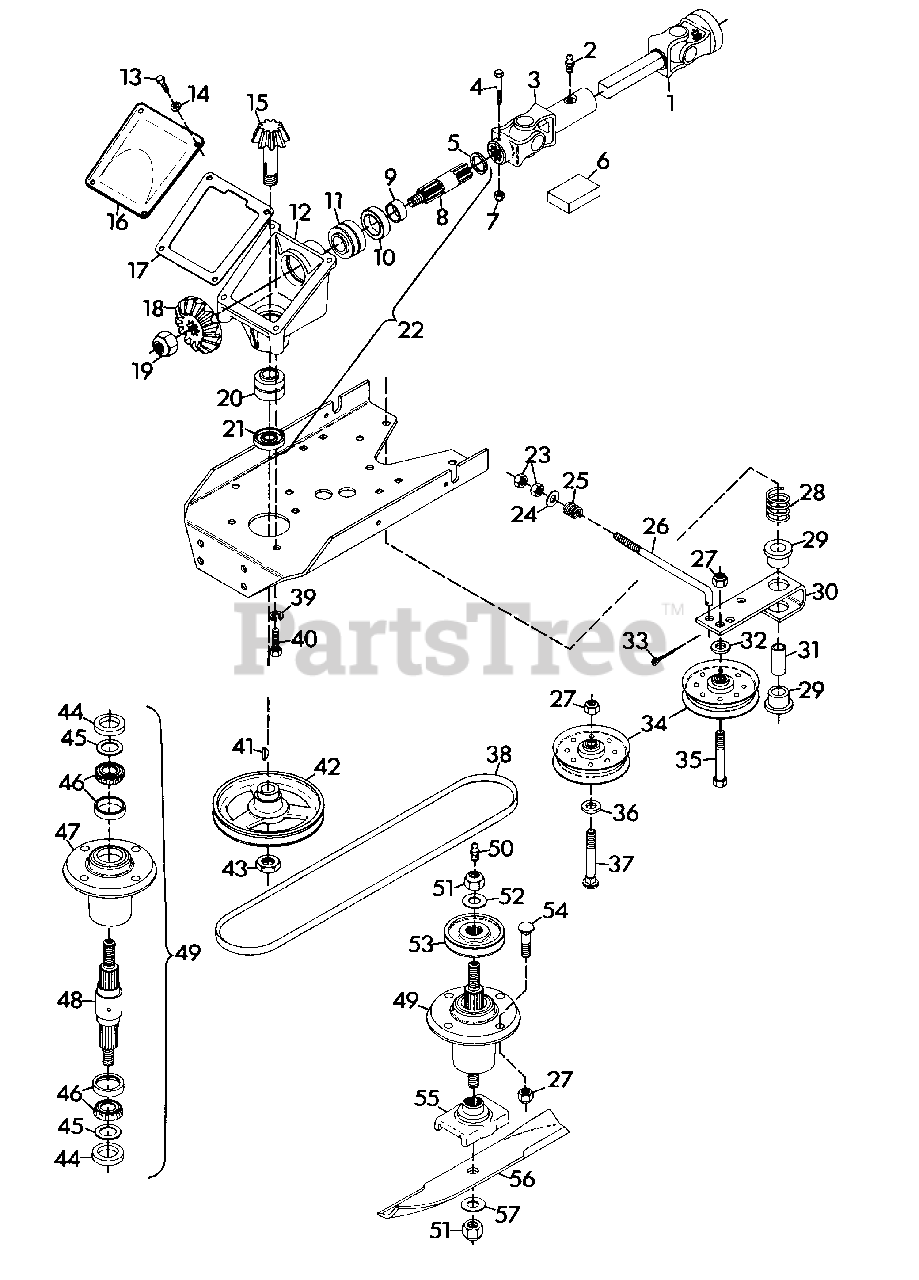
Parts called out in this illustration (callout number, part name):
1	SHAFT, PROP. SQ. BAR
2	FITTING, LUBE 1/4-28
3	U-JOINT, FEMALE END
4	BOLT, HEX 1/4-20X2
5	RING, RETAINING 1.000 SHAFT
6	KIT, REPAIR UNIVERSAL JOINT ROCKWELL STD.
6	KIT, REPAIR UNIVERSAL JOINT NEAPCO 1605X
7	NUT, LOCK 1/4-20
8	SHAFT, DRIVE
9	SPACER
10	SEAL, OIL 1.25X1.987X.250
11	ASSEMBLY, BEARING 1.000X1.980X1.243
12	CASTING, GEAR BOX
13	BOLT, HEX 1/4-20X.50
14	WASHER, LOCK 1/4
15	SHAFT, GEAR PINION
16	COVER, GEAR HOUSING
17	GASKET, GEAR HOUSING
18	GEAR, BEVEL
19	NUT, LOCK 3/4-10
20	ASSEMBLY, BEARING .750X1.781X1.499
21	SEAL, OIL 1.250X1.686X.313
22	ASSEMBLY, DRIVE 50" MOWER
23	NUT, HEX 3/8-24
24	WASHER, FLAT .406X.812X.065
25	SPRING, COMP. TYPE 1X.78X338 LB/IN
26	ROD, IDLER
27	NUT, LOCK 3/8-16
28	SPRING, COMP.
29	BUSHING, NYLON .760X1.00X.600
30	ARM, IDLER PIVOT
31	SPACER
32	SPACER, IDLER .406X.750X.188
33	PIN, COTTER 3/32X1.00
34	SHEAVE, IDLER
35	BOLT, HEX 3/8-16X2.00
36	WASHER, FLAT .438X1.000X.083
37	BOLT, 3/8-16X1.75 RD HD SQ NK
38	BELT, V .500X.312X126.3
39	WASHER, LOCK 1/2
40	BOLT, HEX 1/2-13X1.00
41	KEY, WOODRUFF .188X.625 HARD
42	SHEAVE, 1/2X6.50
43	NUT, JAM 3/4-10 HEX HEAVY
44	SEAL, STEEL
45	WASHER, FLAT .975X1.970X.030
46	ASSEMBLY, BEARING
47	HOUSING, BEARING
48	SHAFT, SPINDLE
49	ASSEMBLY, SPINDLE
50	FITTING, LUBE 1/8(LEFT AND RIGHT SPINDLE)
50	FITTING, LUBE .125 EXT.(CENTER SPINDLE)
51	NUT, LOCK 5/8-11
52	WASHER, FLAT .687X1.312X.122/.146
53	SHEAVE, SPINDLE
54	BOLT, 3/8-16X1.25 RD HD SQ NK
55	CRADLE, BLADE
56	BLADE
57	WASHER, FLAT .656X1.312X.095
